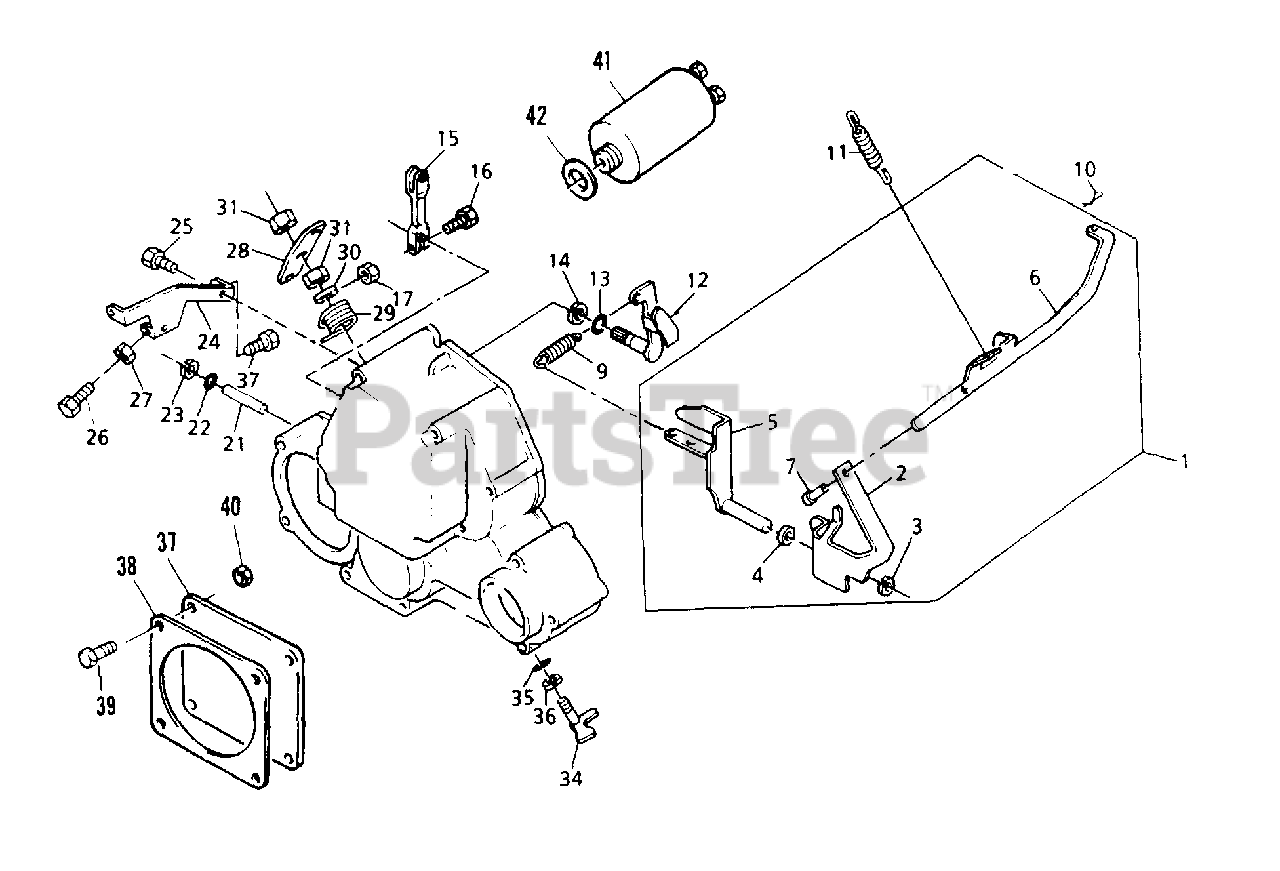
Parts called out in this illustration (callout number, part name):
1	LEVER ASSEMBLY
2	LEVER
3	CIRCLIP
4	WASHER
5	LEVER
6	LINK
7	PIN
9	SPRING
10	PIN
11	SPRING
12	ARM
13	"O" RING
14	CIRCLIP
15	LEVER
16	SCREW
17	NUT
21	SHAFT
22	"O" RING
23	CIRCLIP
24	STAY
25	SCREW
26	SCREW
27	NUT
28	LEVER
29	SPRING
30	WASHER
31	NUT
34	ARM
35	"O" RING
36	CIRCLIP
37	PLATE
38	GASKET
39	SCREW
40	NUT
41	SOLENOID - fuel shut off
42	WASHER
